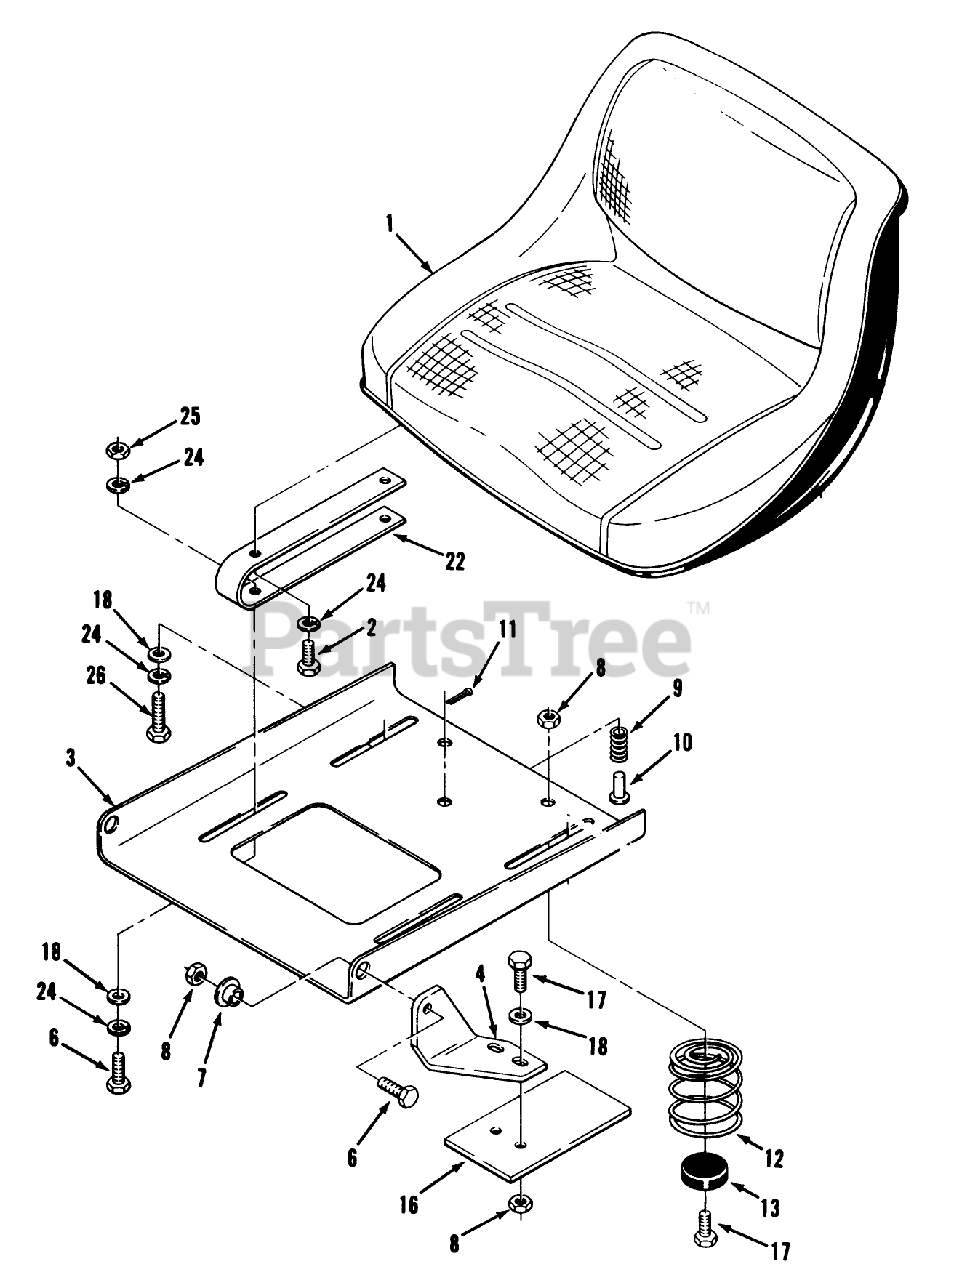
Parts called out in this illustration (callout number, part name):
4	BRACKET-PIVOT R.H *B (NS)
7	BUSHING
9	SPRING-SEAT SWITCH
12	SPRING-SEAT NYLON
13	BUMPER
18	WASHER 5/16 SAE
